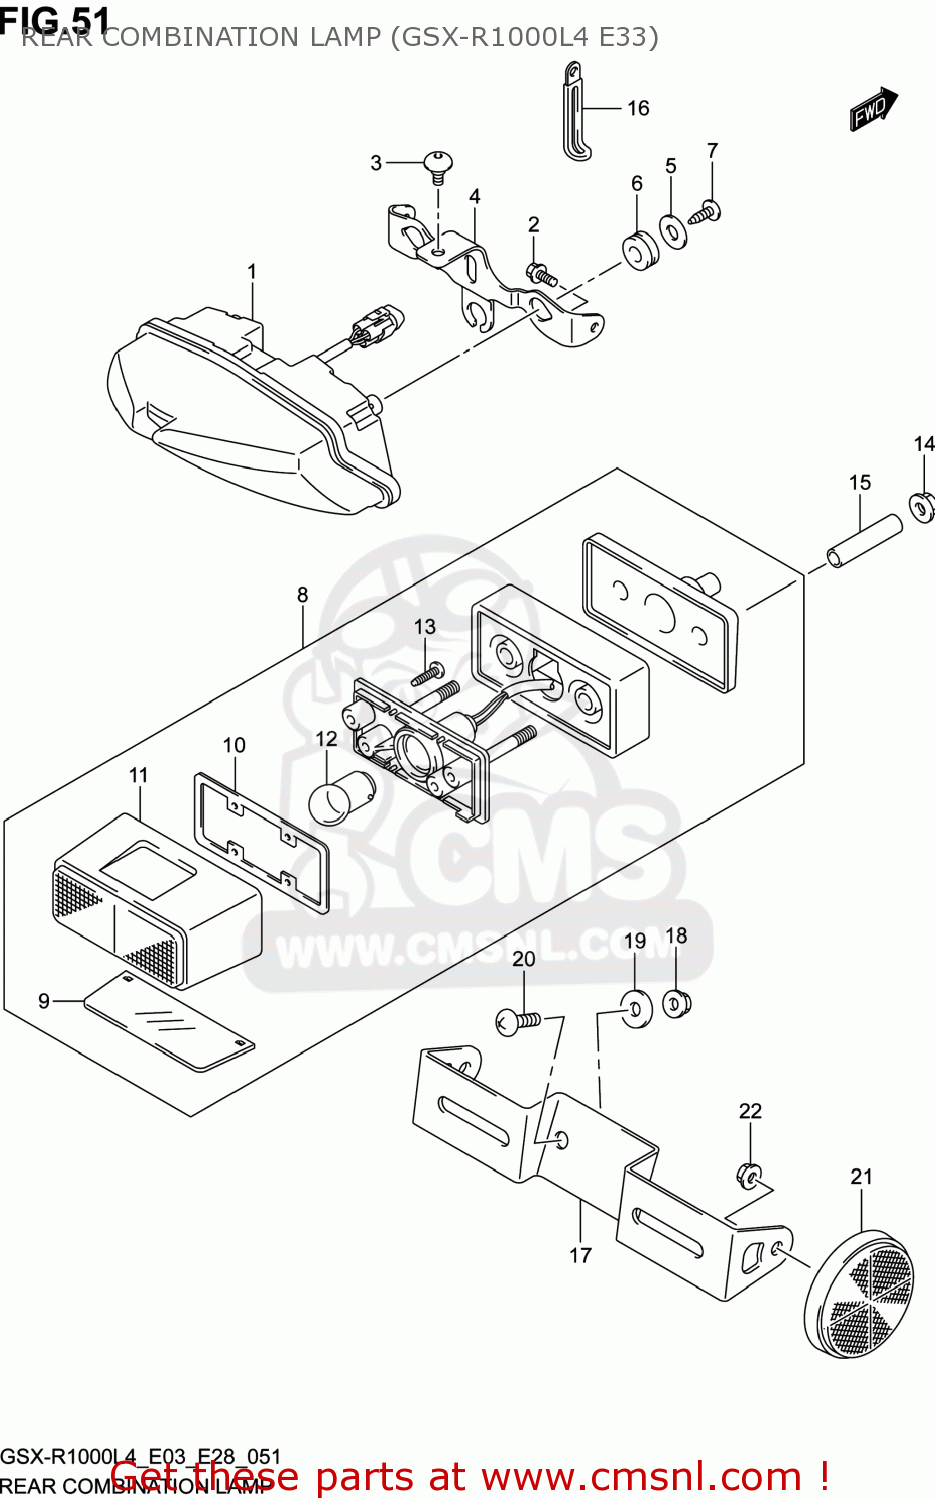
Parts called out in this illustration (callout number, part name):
1	LAMP ASSY,RR COMBINATION
2	BOLT(5X12)
3	SCREW(6X12)
4	BRACKET,RR COMBINATION LAMP
5	WASHER(5.5X20X1.2)
6	CUSHION
7	SCREW
8	LAMP ASSY,LICENSE
9	LENS,LICENSE LAMP
10	GASKET (NAS)
11	COVER,LICENSE LAMP
12	BULB(12V5W,BF150-40160A)
13	SCREW
14	NUT
15	SPACER(6.5X9X34)
16	CLAMP(L:45)
17	BRACKET,LICENSE PLATE
18	NUT
19	WASHER(6.5X20X1.2)
20	SCREW
21	REFLECTOR ASSY,RR SIDE
22	NUT
